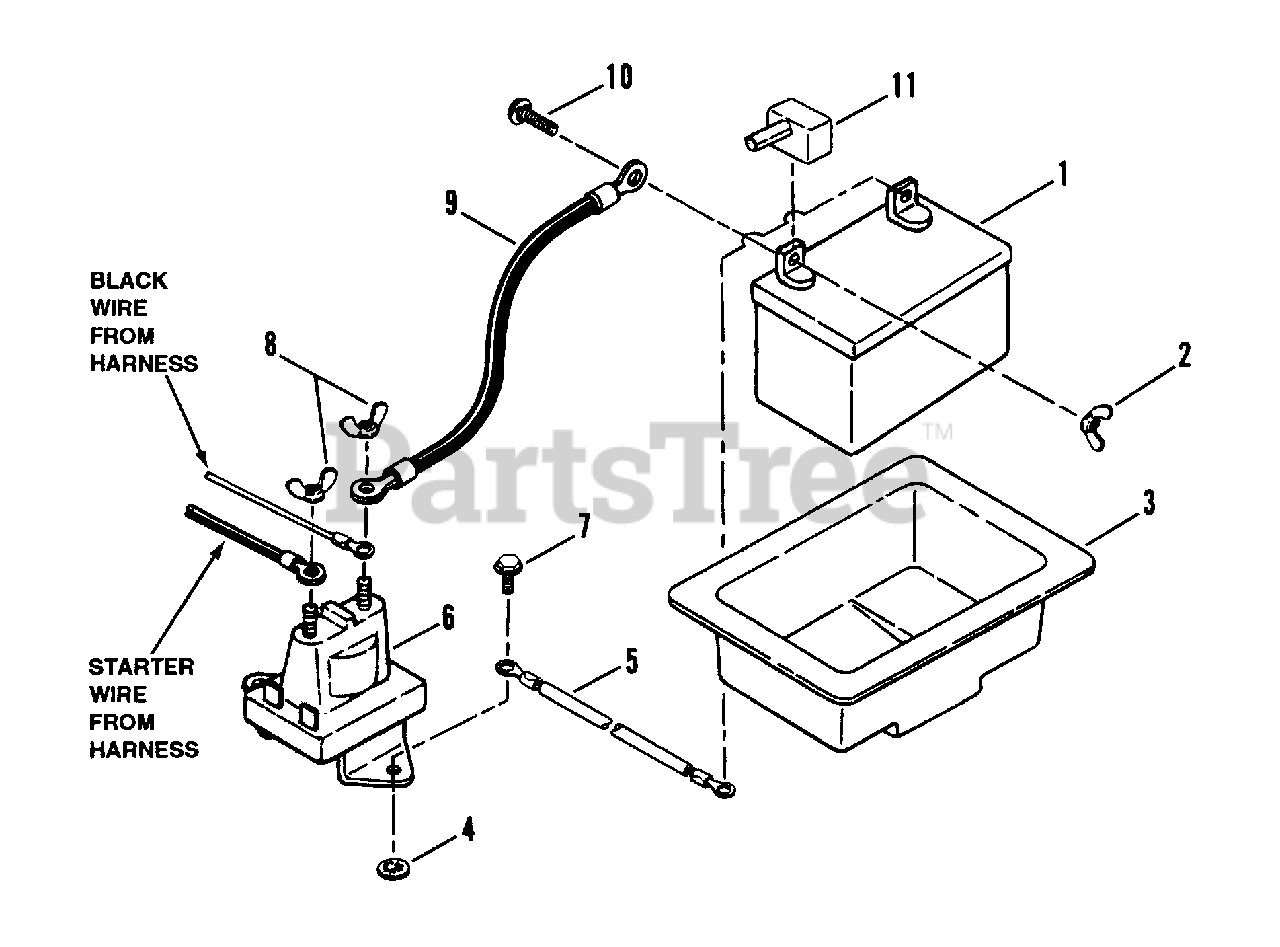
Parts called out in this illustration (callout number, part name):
1	KIT, Battery
2	WING-NUT, 1/4-20
3	TRAY, Battery
4	RETAINER, Screw
5	CABLE, Ground (Black)
6	SOLENOID
7	SCREW, 1/4-20 x 1/2" Self-Tapping
8	WING-NUT, 1/4-20 Locking
9	CABLE, Positive (Red)
10	BOLT, 1/4-20 x 3/4" Carriage
11	COVER, Positive Terminal
